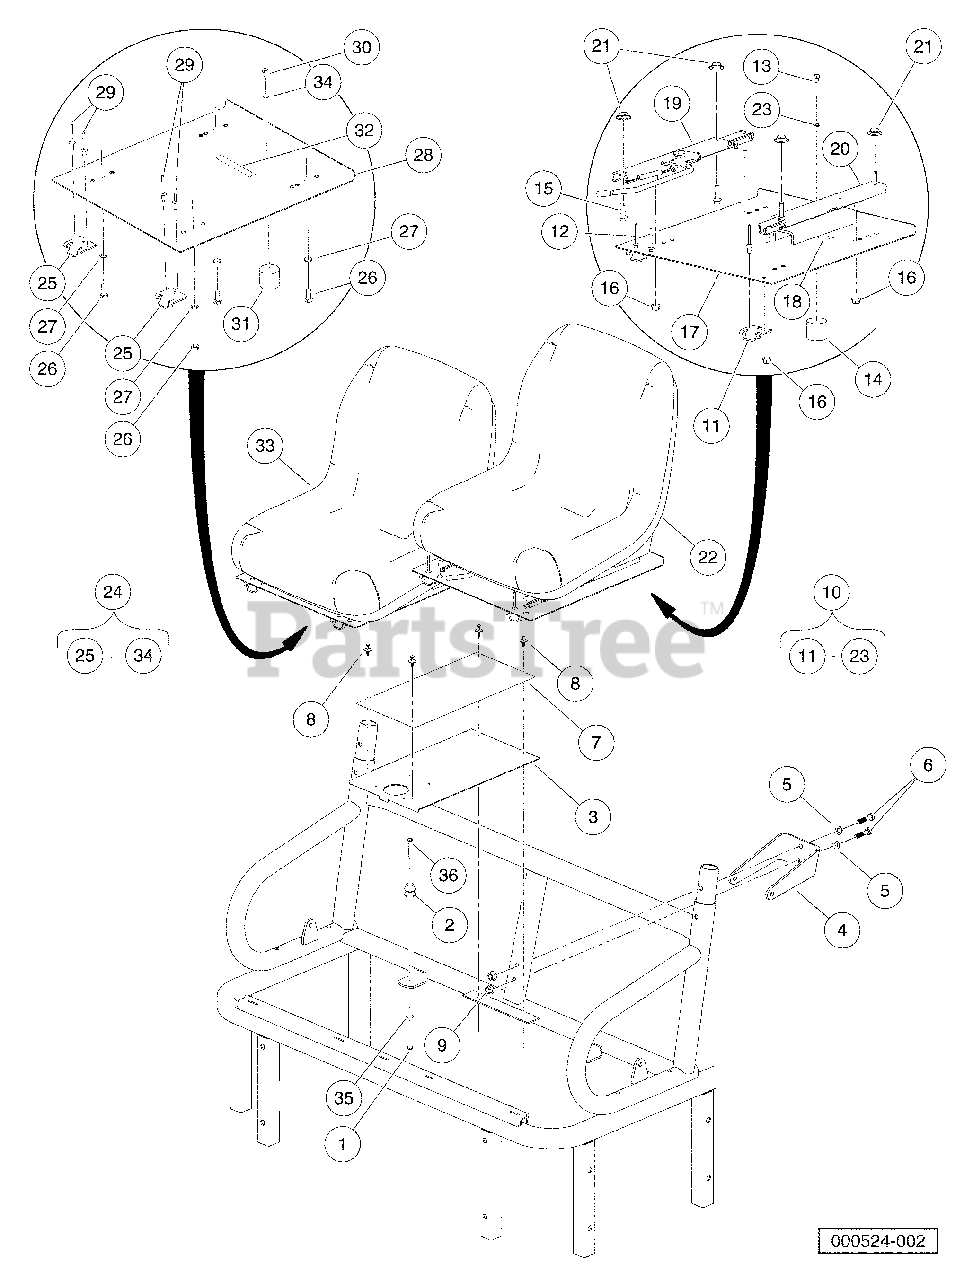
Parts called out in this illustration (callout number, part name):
1	Locknut, M6-100 Nylon Insert
2	Seat Holder Base
3	Pan, Center, Closeout
4	Bracket, Seatbelt, Bolt-On
5	Washer, Hard, M10, Zn-Ni/Blk
6	Bolt, M10 X 45, Zn-Ni
7	Cover, Center Console
8	Rivet, Removable, Tuflok 1/4"
9	Nut, Flanged, M10 x 15, Black
10	Asm, Bracket Seat, Adj, Blk
11	Hinge Plate
12	Rivet, 1/4 X 438 Blind
13	Screw, 6m-100 X 10mm Hex Head
14	Seat Holder Cup
15	Bolt, Flange Head, M8 X 300
16	Nut,m8,all Metal Lock
17	Pan, Seat, Driver Asm
18	Decal, Hot Surface Warning
19	Adjuster, Forward/Aft
20	Adjuster, Slider
21	Washer, Bell
22	Seat, Bucket, Black
23	Lockwasher, 1/4 Helical Split
24	Asm, Bracket Seat, Passenger, Blk
25	Hinge Plate
26	Screw, M8-125 X 22 Hex-Head
27	Lockwasher, 8mm Split
28	Pan, Seat, Passenger
29	Rivet, 1/4 X 438 Blind
30	Screw, 6m-100 X 10mm Hex Head
31	Seat Holder Cup
32	Decal, Hot Surface Warning
33	Seat, Bucket, Black
34	Lockwasher, 1/4 Helical Split
35	Washer, 1/4 Type A Narrow Flat
36	Bolt, M6 X 1 X 45
